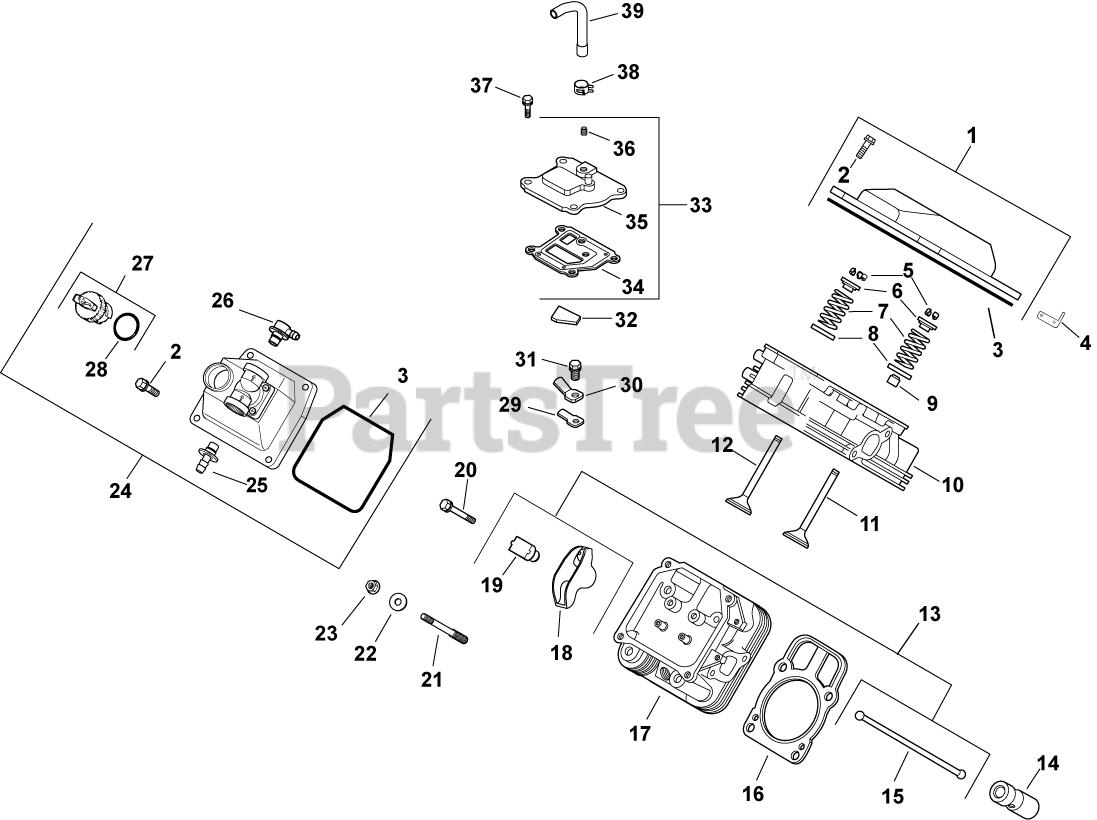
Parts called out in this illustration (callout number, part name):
1	KIT, VALVE COVER-PLAIN
2	SCREW, FLG M6X1.0X30
3	O-RING (YELLOW), VALVE COVER
4	STRAP, LIFTING-USE 25 445 03-S
5	KIT, RETAINER
6	RETAINER, VALVE SPRING - USE 25 173 28-S
7	SPRING, VALVE
8	RETAINER, SPRING
9	SEAL, VALVE STEM - (#2503214S)
10	KIT, #1 CYL HEAD ASSY-(#24318144S)
11	VALVE, INTAKE (STD)
12	VALVE, EXHAUST (STD) - USE 32 016 01-S
13	KIT, VALVE TRAIN
14	LIFTER, HYDRAULIC VALVE-USE 25 351 10-S
15	ROD, PUSH
16	KIT, CYL HEAD GASKET (C17-22)
17	KIT, #2 CYL HEAD ASSY - (#24318150S)
18	ARM, ROCKER
19	PIVOT, ROCKER ARM
20	SCREW, ROCKER ARM PIVOT-USE M-640034-S
21	STUD, M8X1.25
22	WASHER, FLAT 8.6 MM
23	NUT, FLG M8X1.25
24	KIT, VALVE COVER-FUEL PUMP
25	KIT, STRAIGHT FITTING
26	KIT, 90 DEG. FITTING
27	CAP ASSY, OIL FILL (YELLOW)
28	O-RING-USE 24 153 32-S
29	REED, BREATHER
30	RETAINER, REED
31	SCREW, FLG THD FRM M5X.8X10
32	FILTER, BREATHER
33	KIT, BREATHER ASSEMBLY
34	GASKET, BREATHER-USE 24 041 67-S
35	COVER, BREATHER -USE 24 033 01-S
36	PLUG, CTSK PIPE 1/8"
37	SCREW,FLG THD FRM M6X1.0X20-(#25086396S)
38	CLAMP, HOSE (KM)-USE 25 237 31-S
39	HOSE, BREATHER
2401602-S	VALVE, EXHAUST (.25)
2401702-S	VALVE, INTAKE (.25)
